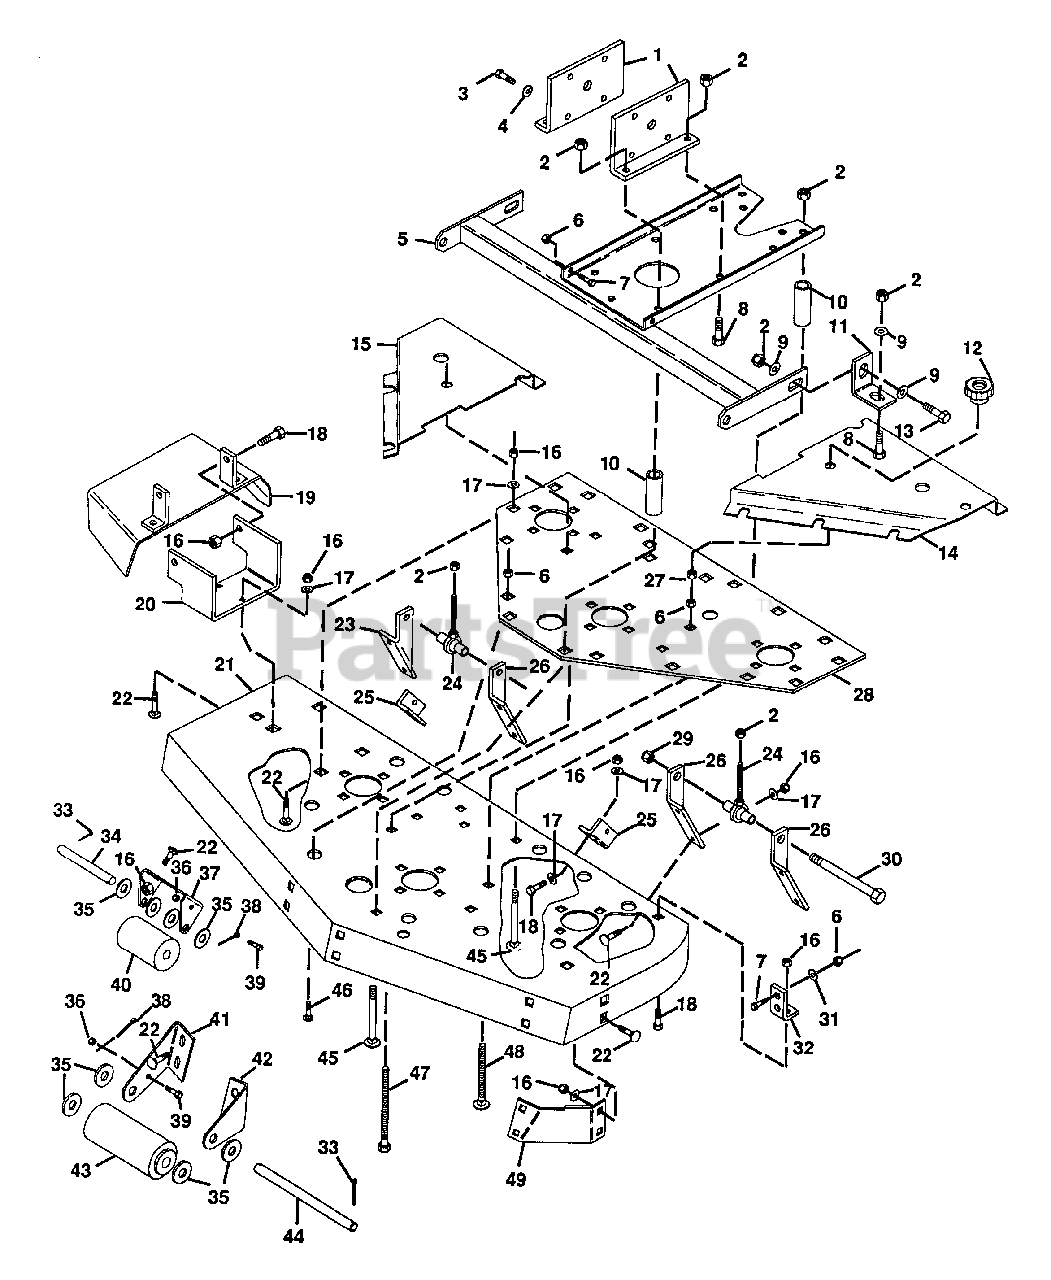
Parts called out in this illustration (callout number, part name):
1	Plate, Gearbox Support
2	Nut, Lock 1/2-13
3	Bolt, Hex 3/8-16x.875
4	Washer, Lock 3/8 Reg.
5	Weldment, Plate
6	Nut, Jam 5/16-18
7	Bolt, Hex 5/16-18x1.25
8	Bolt, Hex 1/2-13x1.25
9	Washer, Flat .531x1 .062x.095
10	Spacer, .850x.546x2.18
11	Bracket, Deck
12	Knob
13	Bolt, Hex 1/2-13x1.50
14	Cover, Belt L.H.
15	Cover, Belt R.H.
16	Nut, Lock 3/8-16
17	Washer, Flat .406x812x.065
18	Bolt, Hex 3/8-16x1.00
19	Weldment, Discharge Chute
20	Bracket, Discharge
21	Weldment, 60" Deck
22	Bolt, 3/8-16x1.00 Rd Hd Sq Nk
23	Plate, Rear Adjustment
24	Rod, End
25	Bracket, Lift
26	Plate, Rear Adjustment
27	Nut, Lock 5/16-18
28	Plate, Support
29	Nut, Lock 3/4-10
30	Bolt, Hex 3/4-10x3.50
31	Washer, Flat .344x.688x.065
32	Bracket, Lift Pivot
33	Pin, Cotter .25x1.0
34	Rod
35	Washer, Flat .656x1 .31x.095
36	Nut, Hex 1/4-20
37	Bracket, Roller
38	Pin, Cotter .25x2.0
39	Bolt, Hex 1/4-20x.75
40	Roller, Gauge
41	Bracket, R.H. Roller
42	Bracket, L.H. Roller
43	Roller, Gauge
44	Shaft, Center Roller
45	Bolt, 1/2-13x3.75 Rd Hd Sq Nk
46	Bolt, Carriage 5/16-18x1.0
47	Bolt, Hex 5/16-18x3.50
48	Bolt, 5/16-18x4.00 Rd Hd Sq Nk
49	Baffle, Front
